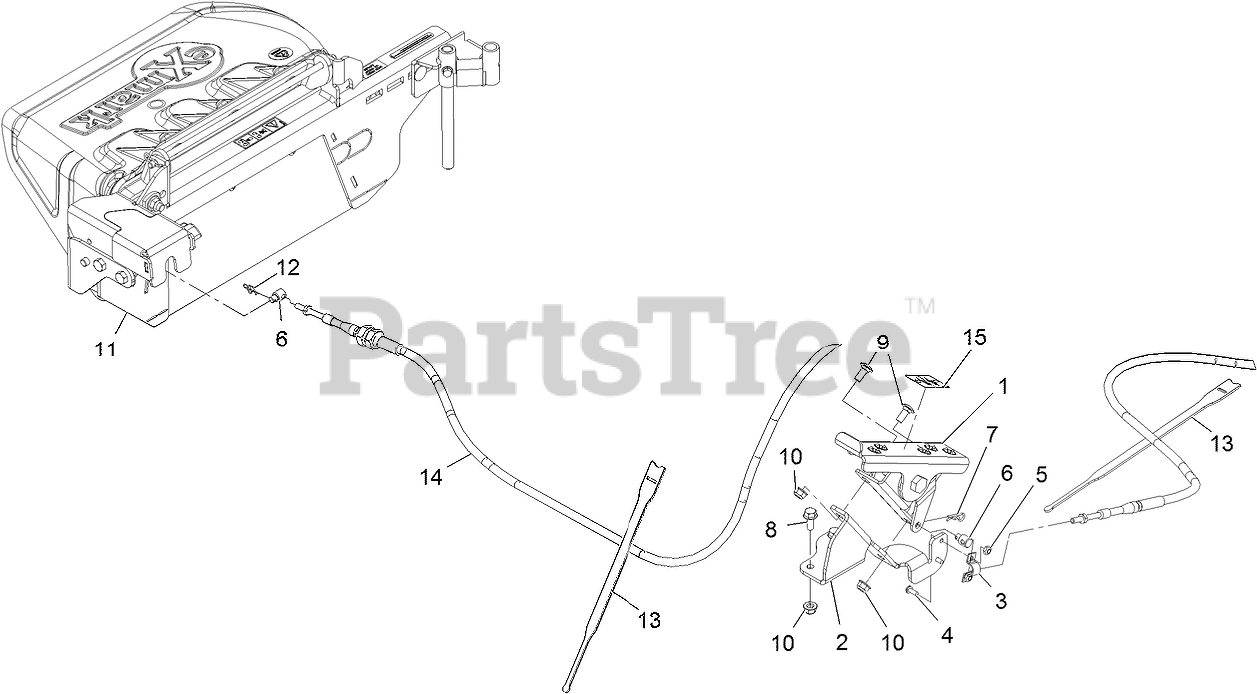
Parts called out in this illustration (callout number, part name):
1	ASM, PEDAL, OCD GATE
2	MOUNT-PEDAL, OCD
4	SCREW-PPH
5	NUT-LOCK, NI
6	PIVOT, CONTROL CABLE
7	PIN-COTTER
8	SCREW-HHF
9	SCREW-CARR
10	NUT-HF, NI
11	ASM, OCD
12	PIN-COTTER, LOCKING
13	STRAP-VELCRO, CABLE TIE
14	CABLE-DISCHARGE GATE
15	DECAL-OCD OPERATION
